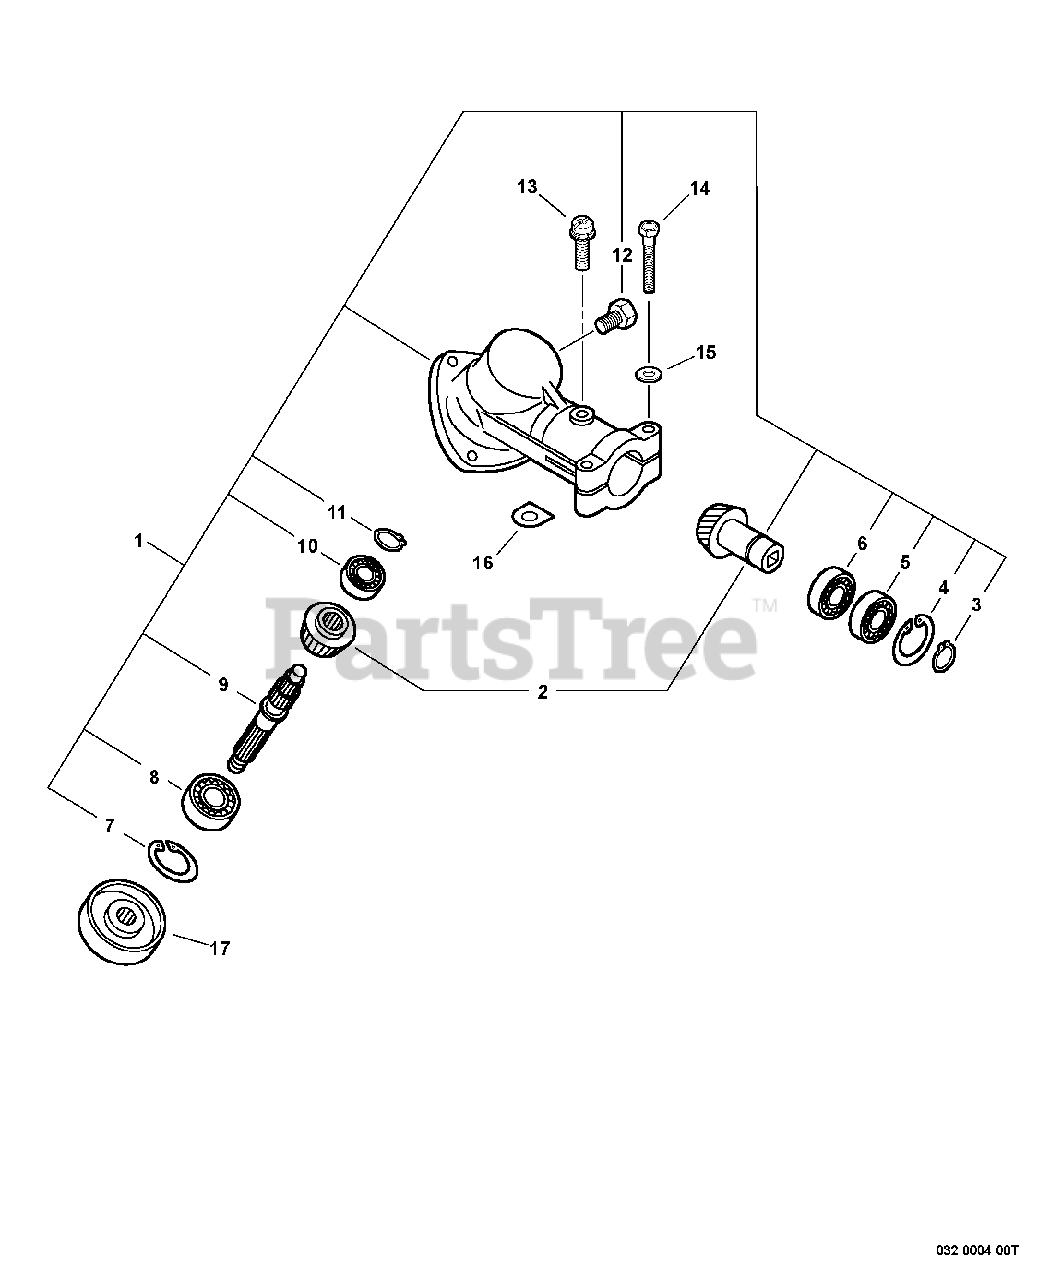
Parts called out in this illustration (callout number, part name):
1	GEAR CASE ASSY
2	GEAR SET
3	RING, RETAINING - 10
4	RING, RETAINING - 22
5	BEARING, BALL - 6900Z
6	BEARING, BALL - 6900
7	RING, RETAINING - 42
8	BEARING, BALL - 629
9	GEAR - SHAFT
10	BEARING, BALL - 609
11	RING, RETAINING - 12
12	BOLT - 8X8
13	SCREW - 5X12
14	BOLT - 5X30
15	WASHER - 5
17	ADAPTOR, BLADE - UPPER
